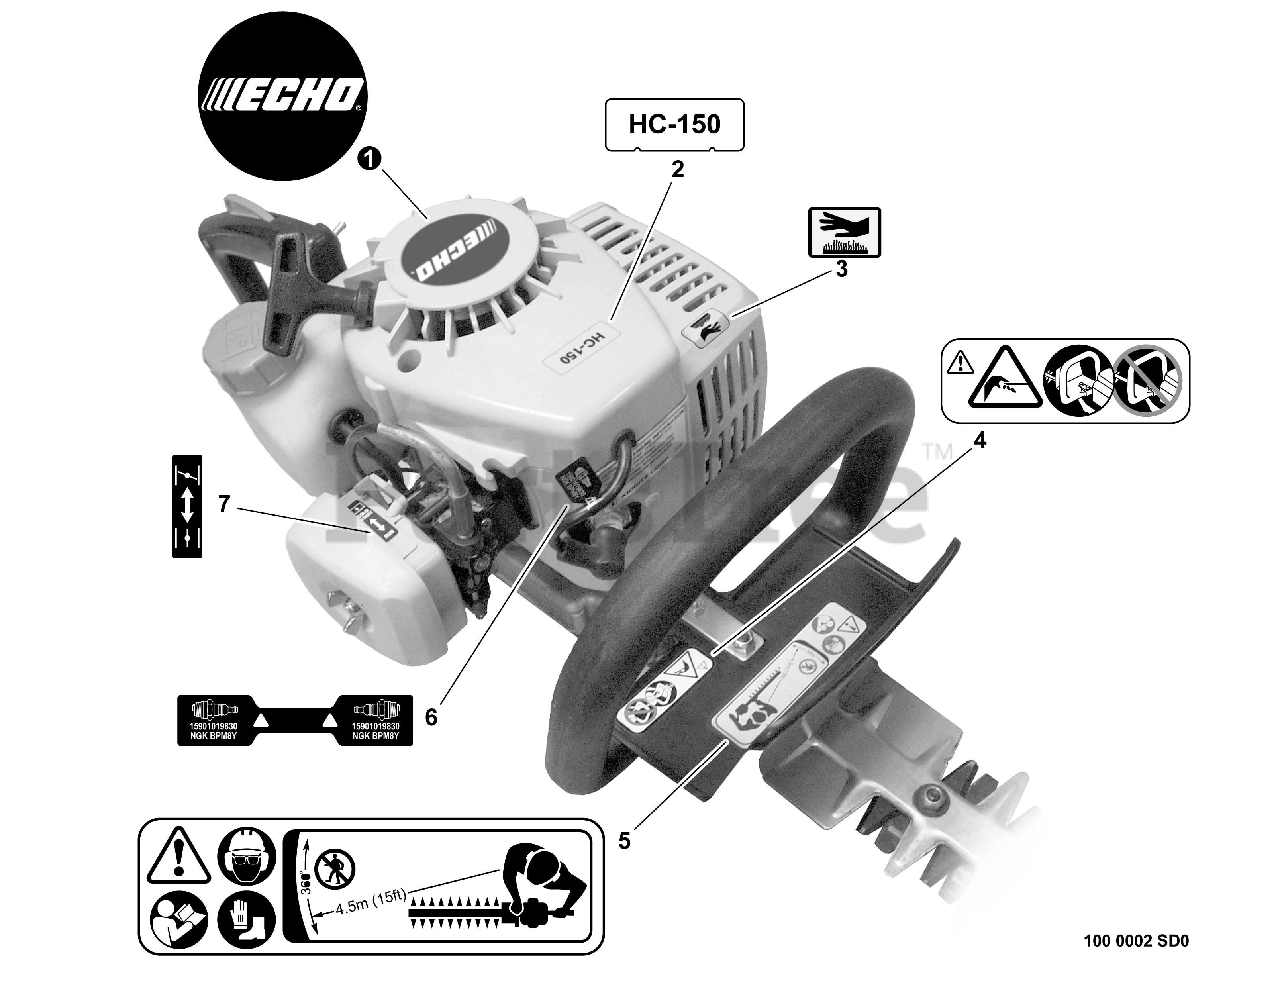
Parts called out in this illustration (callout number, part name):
1	LABEL - ECHO
2	LABEL - MODEL HC-150
3	LABEL - HOT SURFACE
4	LABEL - CAUTION
5	LABEL - CAUTION
6	LABEL - SPARK PLUG -- BPM-8Y
7	LABEL - CHOKE
